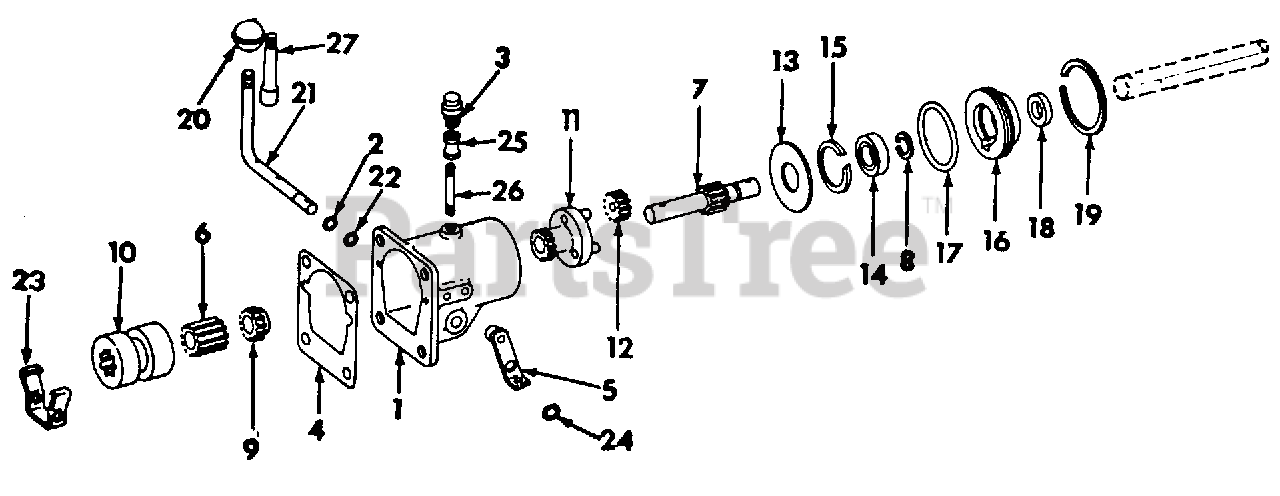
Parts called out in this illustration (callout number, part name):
1	Housing, Creeper Drive
2	O-Ring, 3/8 X 1/2 X 1/16
3	Breather, Creeper Drive Housing
4	Gasket, Creeper Drive Housing
5	Lever Assy, Creeper Shift Poppet
6	Coupling Assy, Driven
7	Shaft, Creeper Drive Input
8	Ring, Creeper Drive Input Shaft Snap
9	Coupling, Direct Drive
10	Collar, Shifter
11	Carrier Assy, Planet
12	Gear, Planet
13	Washer, Planet Gear Thrust
14	Bearing, Creeper Input Shaft Ball
15	Ring, Input Shaft Brg Snap
16	Cage, Input Shaft Brg
17	O-Ring, 2-7/16 X 2-5/8 X 3/32
18	Seal, Input Shaft Brg Cage Oil
19	Ring, Input Shaft Brg Cage Retainer Snap
20	Knob, Creeper Shift Lever
21	Lever, Creeper Shift
22	O-Ring, 1/4 X 3/8 X 1/16
23	Yoke, Creeper Shift
24	Spacer, Poppet Lever
25	Coupler, 1/8 Pipe
26	Nipple, 1/8 X 2-1/4 Pipe
27	Extension, Shift Lever
